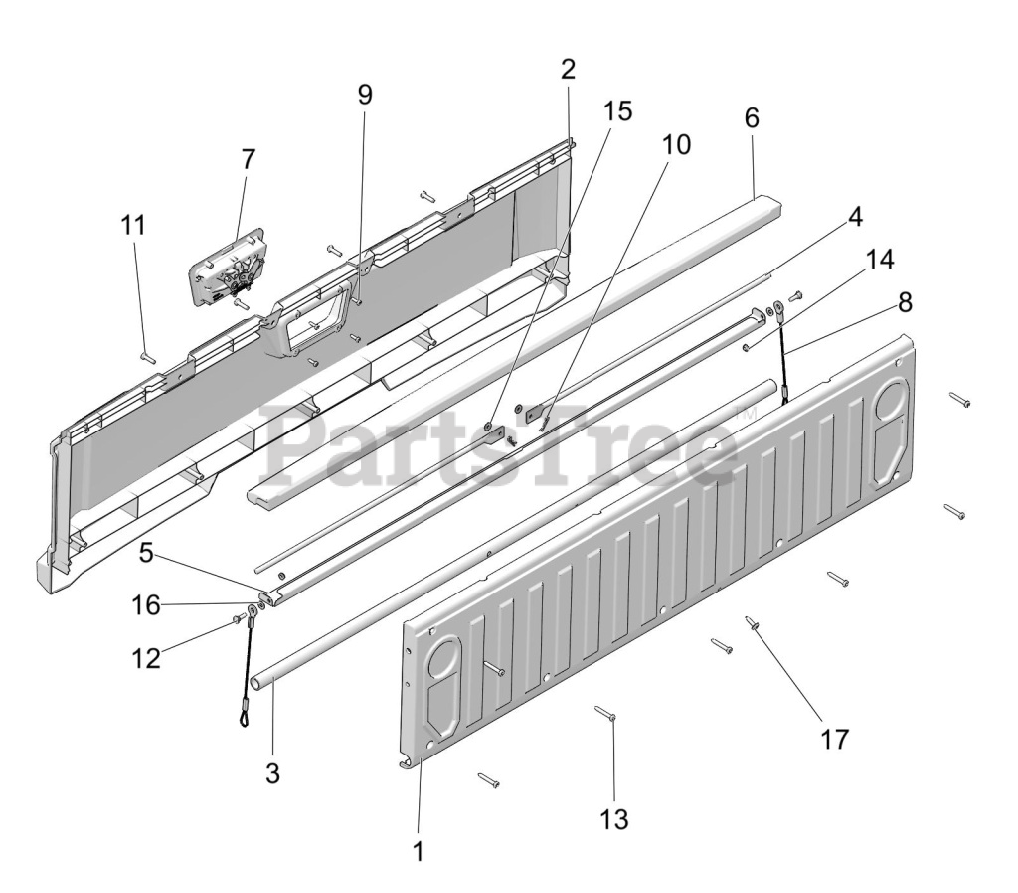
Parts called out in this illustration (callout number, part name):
1	PANEL-TAILGATE-INNER-BLK
2	PANEL-TAILGATE-OUTER-BLK
3	TUBE-TAILGATE PIVOT-BLK
4	ROD- TAILGATE
5	BRKT-TAILGATE-GALV
6	CAP-TAILGATE-BLK
7	LATCH-PADDLE
8	TAILGATE CABLE
10	PIN-HITCH-3/32-Y
11	SCR-#14X1 HI/LO-PH-PN TRX-M
12	BLT-SHLDR .188X.188X.25-20
13	SCR-TXPH-#14X1.75 HI/LO RIE
14	NUT-HEX-1/4-20-NTE ZY3 NYL
16	WASHER- FLAT(10) *
17	SCR-1/4-20X1.00 TR/TX-M
